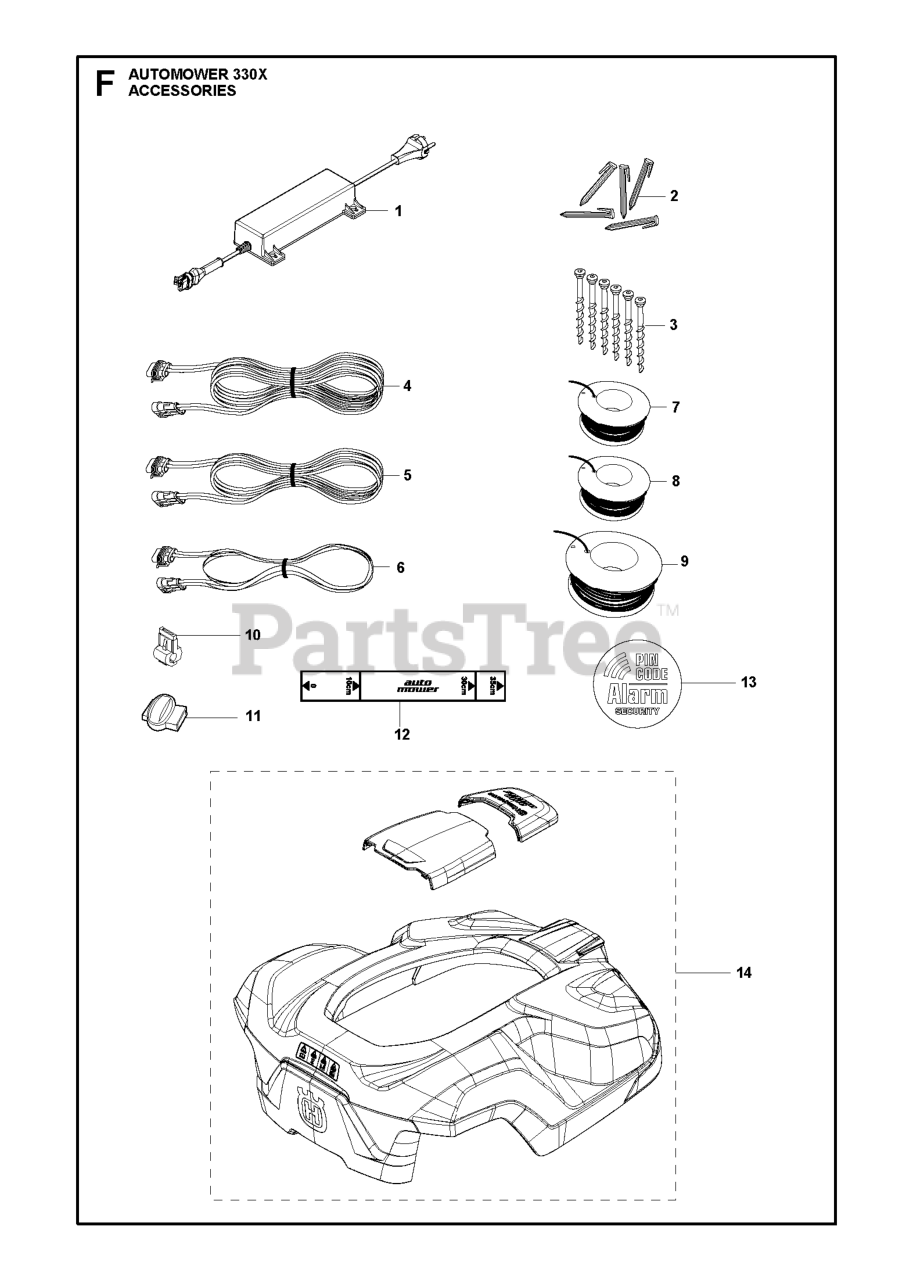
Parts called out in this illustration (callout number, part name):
1	POWER UNIT POWER SUPPLY TYPE F
2	STAPLES (100 CT BAG)
2	STAPLE 100 PCS, BLISTER
3	SCREW 3 PCS, BLISTER PACK
3	SCREW KIT CS
4	LOOM LOW VOLTAGE CABLE 20 METE
5	LOOM LOW VOLTAGE CABLE 10 METE
6	LOOM LOW VOLTAGE CABLE 3 METER
7	WIRE 150M, BLISTER
7	LOOP WIRE 150M
8	LOOP WIRE 250M
9	WIRE 500M
10	BRAKER
10	CONNECTOR 5 PCS, BLISTER
11	SPLICE CONNECTOR 50 PCS/PK
11	SPLICE KIT
11	COUPLER SPLICER, 5 PCS,
12	RULER / CENTIMETERS
13	LABEL SECURITY
